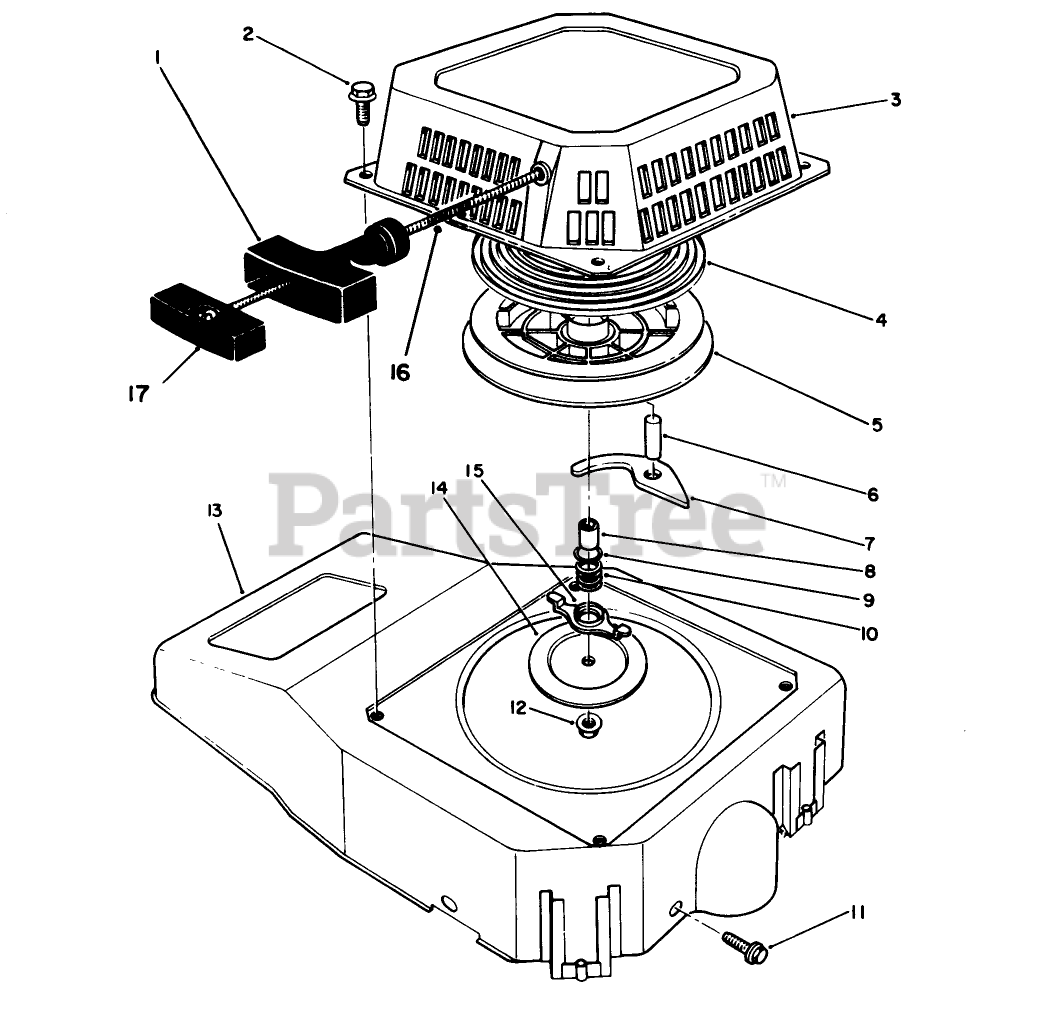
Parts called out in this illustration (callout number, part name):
1	HANDLE
2	SCREW-HHF
3	Case-Recoil
4	SPRING
8	Spacer
9	WASHER
10	Spring-Friction
13	SHROUD
14	PLATE
15	Guide-Paw
16	ROPE-STARTER
17	RETAINER HANDLE
